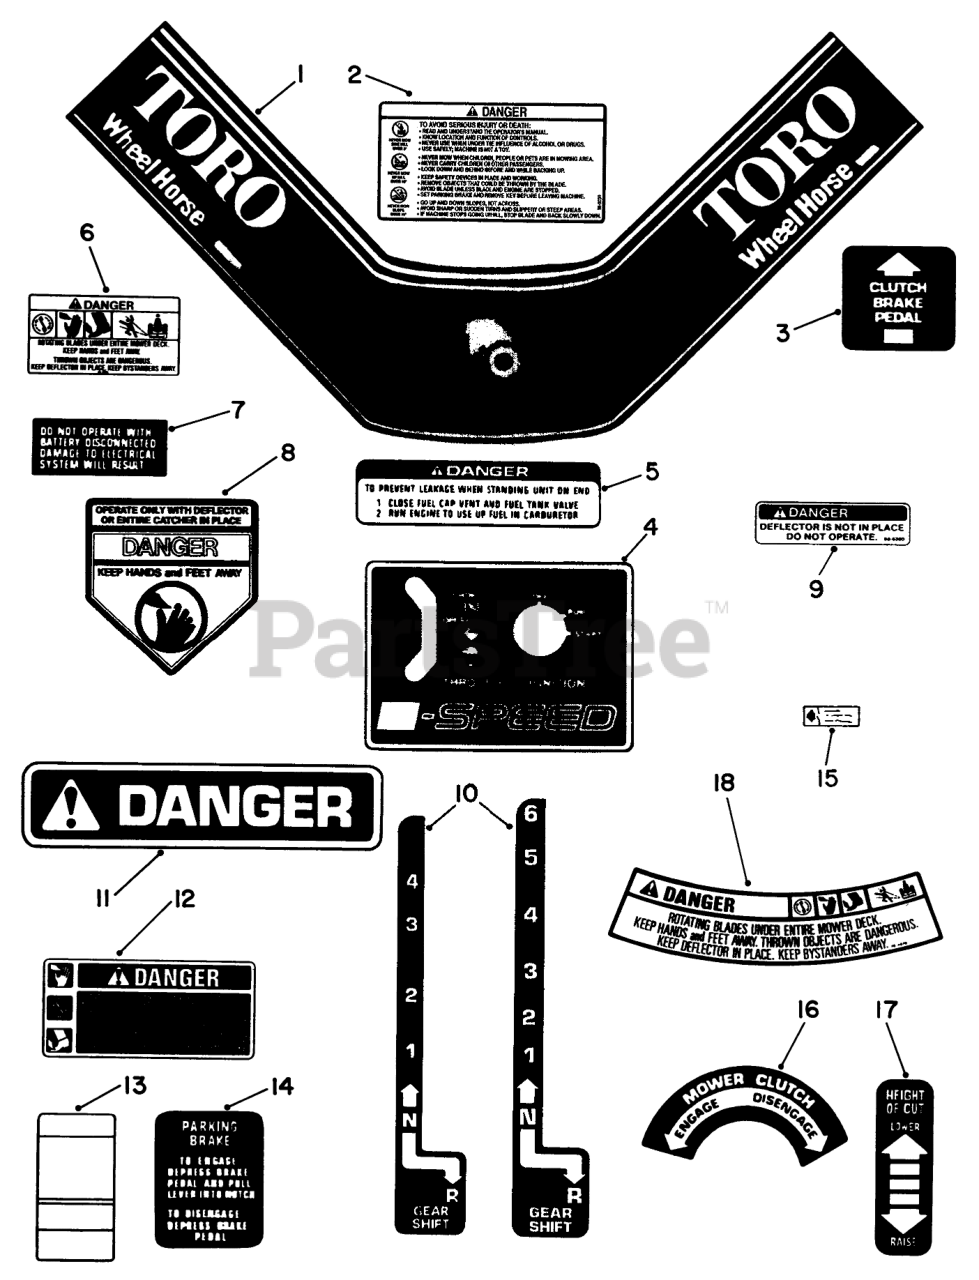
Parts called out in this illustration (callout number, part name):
1	DECAL-SHROUD 110-4
2	DECAL - DANGER
3	DECAL CLUTCH & BRAKE
4	DECAL-MODEL 110-4
5	DECAL-DANGER
6	DECAL-DANGER, THROWN OBJECT
7	DECAL ELECT SYSTEM
8	DECAL-DANGER
9	DECAL-DANGER
10	DECAL-SHIFT 4-SPD
11	Danger Decal
12	DECAL-DANGER
13	MAINTENANCE-DECAL
14	DECAL PARKING BRAKE
15	DECAL-PTO BELT ADJ
16	DECAL MOWER CLUTCH
17	DECAL-HOC
18	DECAL - DANGER
